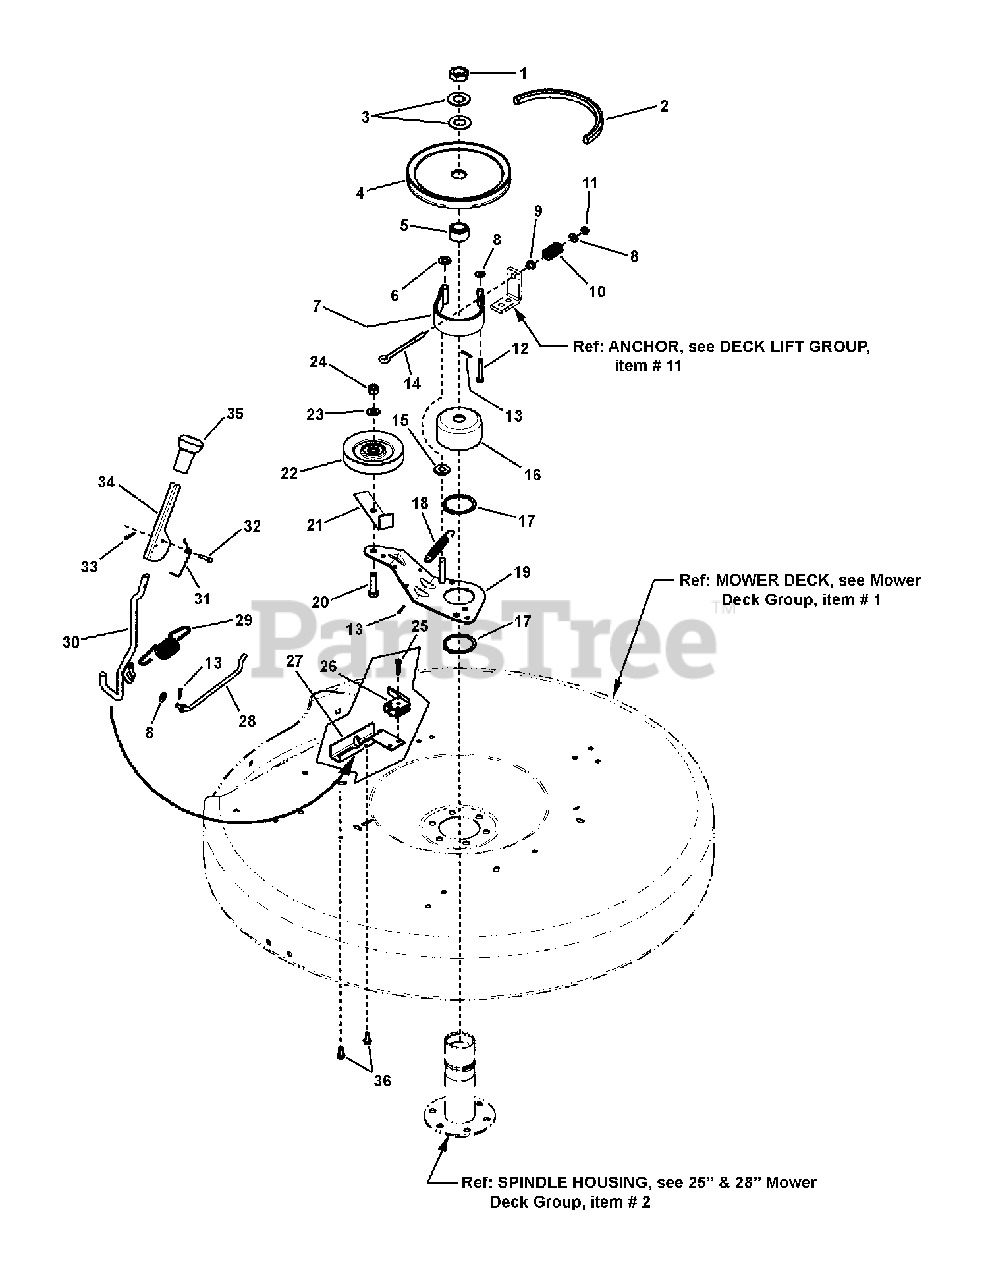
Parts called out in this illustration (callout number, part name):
1	NUT, 3/4-16 Hex Jam, GR 8
2	* BELT, Drive (72.75 AA Section)
3	WASHER, 49/64 I.D. x 1-1/2 O.D. Flat
4	PULLEY, Deck
5	PULLEY, Hub (Powdered Metal)
6	WASHER, 3/8 Flat SAE
7	BAND, Brake (Formed)
8	WASHER, Flat, 1/4
9	BUSHING, Flange .27 x .35 x .4
10	SPRING, Rectangular Wire Die, Blue
11	NUT, 1/4-20 Hex Top Lock
12	PIN, 1/4 x 1-5/8 Clevis
13	PIN, 3/32 X 3/4, GR5, Cotter, Zinc/Clear
14	EYE-BOLT, 1/4-20 x 4"
15	SPACER, .39 x 1.0 x .31 Nylon
16	DRUM, Brake Spindle (3 OD, 1.6 Tall)
17	RING, 2 External Retaining
18	SPRING, Extension, 4 x 1/2 Diameter
19	WELDMENT, Idler Arm
20	SCREW, 3/8-16 x 1-1/2 Hex Head Cap, GR 5
21	RESTRICTOR, Belt
22	PULLEY, Idler (3/8 ID, 4 OD)
23	WASHER, 3/8 Flat
24	NUT, 3/8-16, Nylock, Zinc/Clear
25	SCREW, #10-32 x 1 Hex Washer Head Self-Tap
26	SWITCH, Deck Interlock (NO)
27	MOUNT, Handle/Switch
28	ROD, Idler Control
29	SPRING, Blade Handle
30	WELDMENT, Blade Engagement Handle
31	SPRING, Torsion, Flip Handle
32	PIN, 3/16 x 1 Clevis
33	PIN, 3/32 x 1/2 Cotter
34	HANDLE, Blade Engagement (Flip)
35	GRIP, Handle
36	SCREW, 1/4-20 x 5/8 Hex Washer Head Self-Tap
